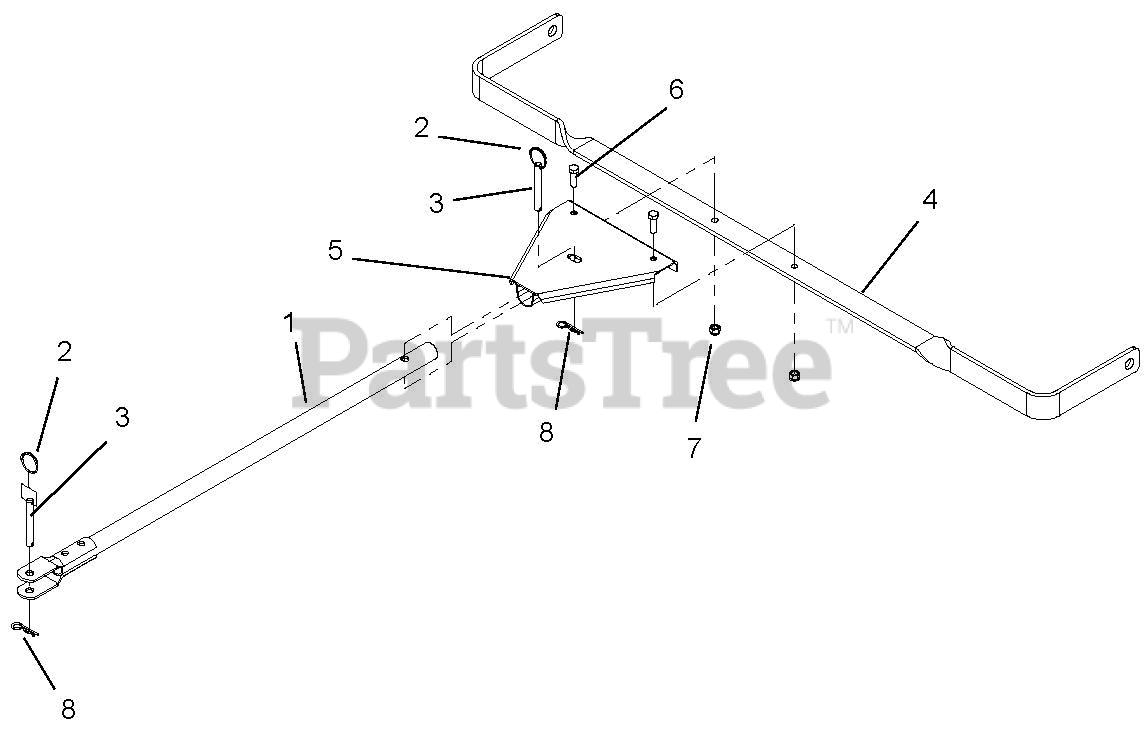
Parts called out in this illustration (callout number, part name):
1	Tongue Weldment
2	Ring, Locking
3	Pin, Hitch
5	Hitch Plate Weldment
6	Bolt, Hex .31-18 x 1.00 Gr 5 YWZC
7	Nut, Nylok .312-18 YWZC
8	Pin, Cotter .09 x 1.50 YWZC
